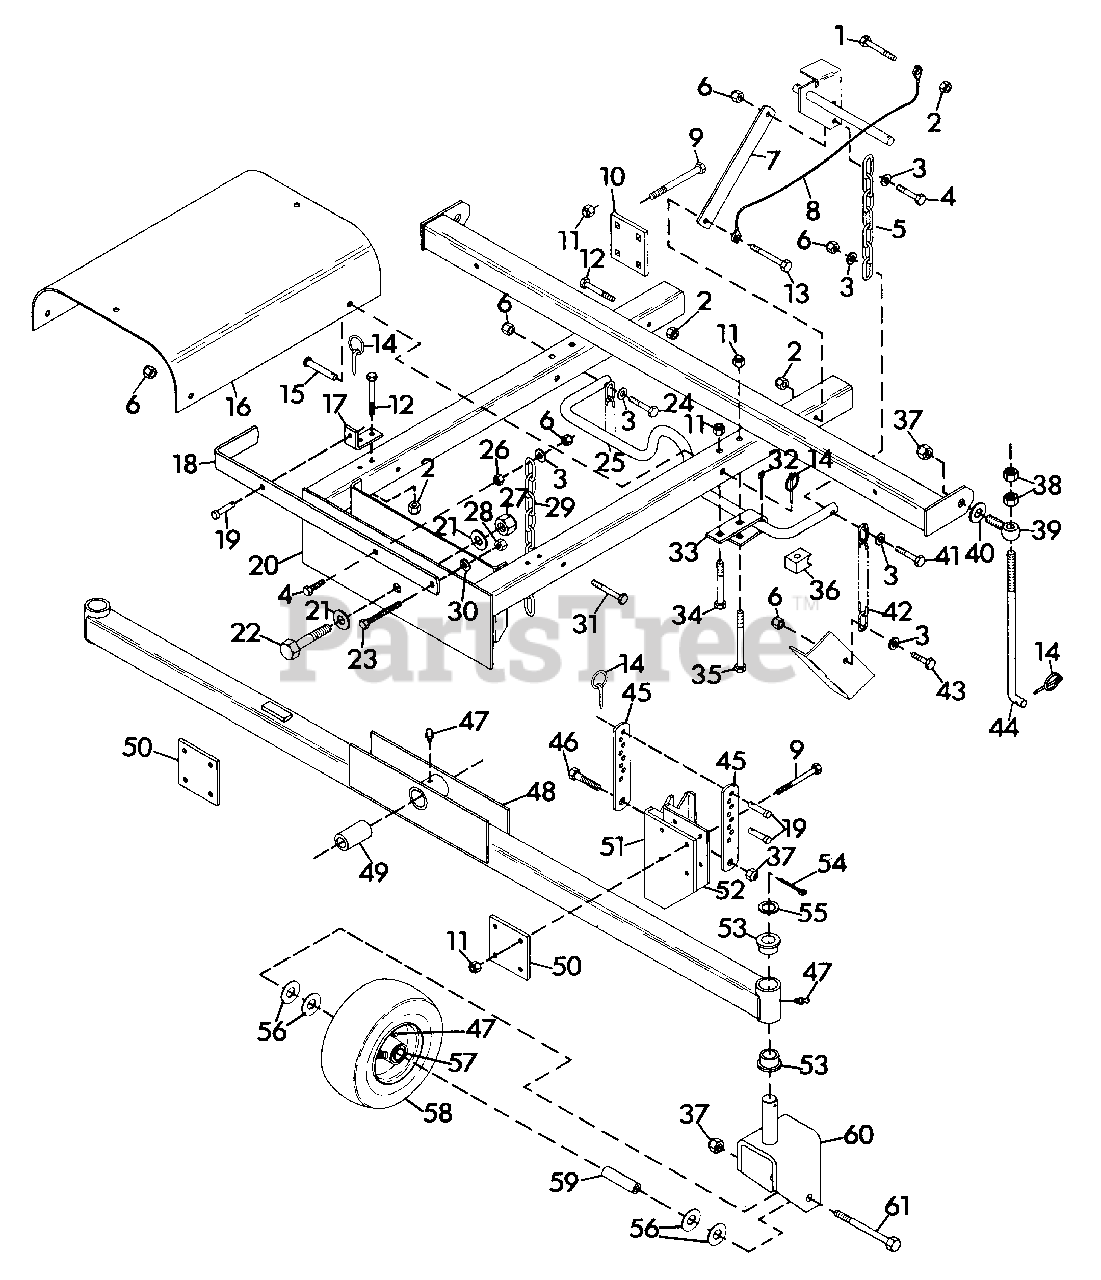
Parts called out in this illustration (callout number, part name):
1	Bolt, Hex 5/16-24x2.25
2	Nut, Lock 5/16-24
3	Washer, Flat .406x.812x.065
4	Bolt, Hex 5/16-18x1.25
5	Chain, Lift
6	Nut, Lock 5/16-18
7	Bar, Deck Lift
8	Cable, Stop
9	Bolt, Hex 3/8-16x3.25
10	Plate, Attachment Clamp
11	Nut, Lock 3/8-16
12	Bolt, Hex 5/16-24x2.75
13	Bolt, Hex 5/16-24x3.5
14	Klik Pin
15	Pin, Clevis 3/8x2.62
16	Guard, PTO Shaft
17	Bracket, Lift Pivot
18	Bar, Lift
19	Pin, Clevis
20	Weldment, Mower Frame
21	Washer, Flat .812x1.469x.130
22	Bolt, Hex 3/4-10x4.50
23	Bolt, Hex 3/8-16x3.00 Special
24	Bolt, Hex 5/16-18x1.50
25	Arm, Pivot
26	Nut, Jam 5/16-18
27	Nut, Lock 3/4-10
28	Nut, Jam 3/8-16
29	Chain, Height Adjustment
30	Washer, Lock 3/8
31	Bolt, Hex 5/16-18x2.50
32	Pin, Cotter 1/8x1.25
33	Bracket, Axle Support
34	Bolt, Hex 3/8-16x3.00
35	Bolt, Hex 3/8-16x4.00
36	Stop, Nylon
37	Nut, Lock 1/2-13
38	Nut, Jam 1/2-13 Hex
39	Bolt, Eye
40	Washer, Flat .500x1.250x.083
41	Bolt, Hex 5/16-18x1.75
42	Chain, Lift
43	Bolt, Hex 5/16-18x1.00
44	Rod, Height Adjustment
45	Strap, Adjustment
46	Bolt, Hex 1/2-13x2.00
47	Fitting, Lube 1/4-28
48	Weldment, Axle
49	Tube, Pivot
50	Plate, Adjustment Clamp
51	Plate, Height Adjustment-L.H.
51	Plate, Height Adjustment-R.H.
52	Plate, Height Adjustment-L.H.
52	Plate, Height Adjustment-R.H.
53	Bushing, Pivot
54	Pin, Cotter .187x1.62
55	Race, Bearing Thrust
56	Washer, Flat .531x1.250x.100
57	Bearing, Gauge Wheel
58	Wheel, Gauge
59	Bushing, Wheel .520x.750x3.312
60	Weldment, Caster Fork
61	Bolt, Hex 1/2-13x5.00
